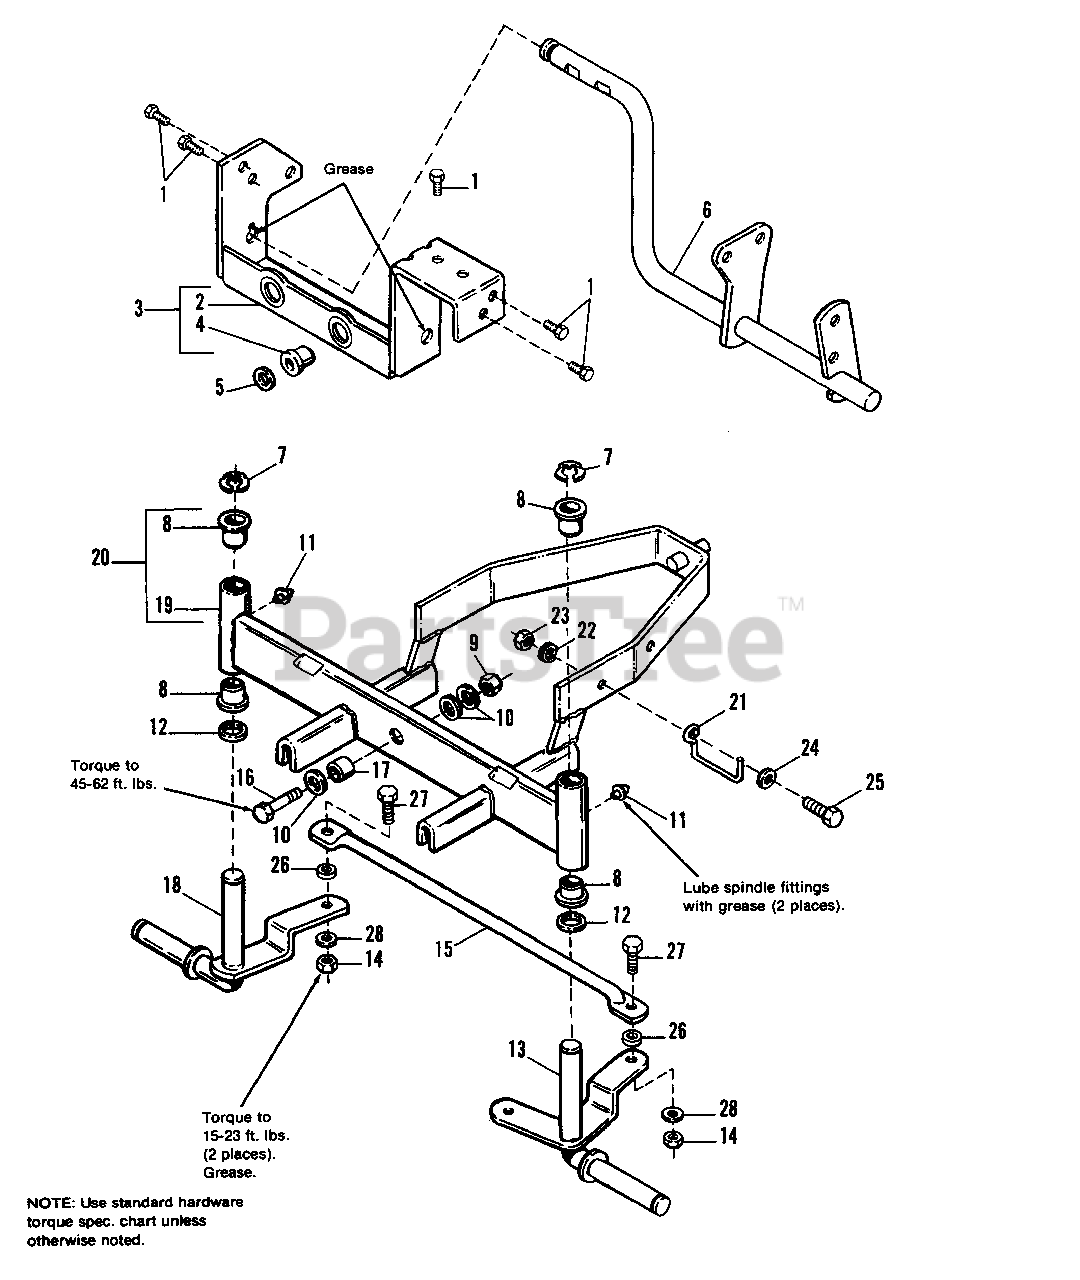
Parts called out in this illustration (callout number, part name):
1	SCREW, Taptite, 5/16-18 x 3/4
3	SUPPORT ASSY., Axle Rear w/ Bushing (Incl. Ref. Nos. 2 & 4)
5	WASHER, 5/8
6	LEVER ASSY., Brake
7	KLIP RING, Ext. 3/4
9	LOCKNUT, Hex, 1/2-13
10	WASHER, Plain, 9/16
11	FITTING, Grease, 1/4-20
12	WASHER
13	SPINDLE ASSY., L.H.
14	LOCKNUT, Hex, 3/8-16
15	ROD ASSY., Tie
16	CAPSCREW, Hex, 1/2-13 x 2-1/4
18	SPINDLE ASSY., R.H.
20	AXLE ASSY., Front (Incl. Ref. Nos. 8 & 19)
21	GUIDE, Drag Link
22	LOCKWASHER
23	NUT, Hex, Full, 5/16-18
24	WASHER, 5/16 Std.
25	CAPSCREW, Hex, 5/16-18 x 1
27	CAPSCREW, 3/8-16 x 1
28	WASHER
